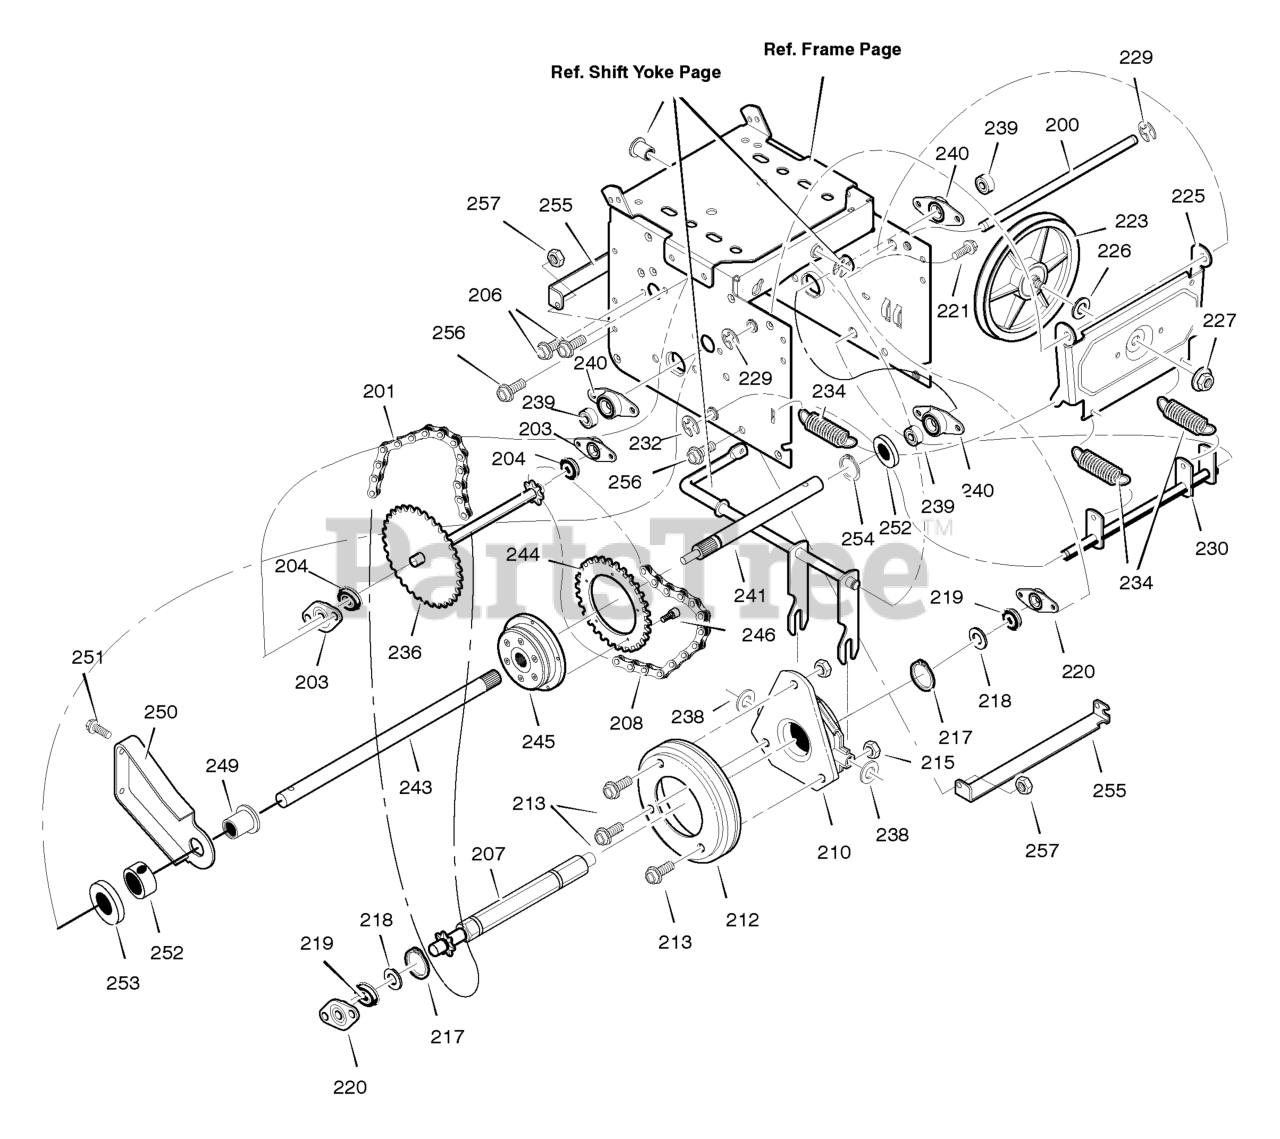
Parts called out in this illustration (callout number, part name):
200	LF AXLE, SWING PLATE YZ
201	CHAIN, ROLLER #420 x 19.00
203	RETAINER ASSY, BEARING
204	BEARING
206	SCREW, TAP 5/16-18 x 0.5
207	ASSY, HEX SHAFT
208	CHAIN, ROLLER #420x18.00 LG
210	BEARING, TRUNION CLUTCH R
212	WHEEL, FRICTION DISC
215	NUT, KEPS HEX 1/4-20
217	RING, RETEXT
219	BEARING, BALL
220	RETAINER, BEARING
221	SCREW, TAP 5/16-18 x .5
223	FRICTION PULLEY
225	LF PLATE, SWINGING YZ
226	SPACER, FRICTION PULLEY
227	NUT, FLANGE LOCK 3/8-24
229	RETAINER, RING
230	ASSY., SPRING LINK -STEERABLE
232	RETAINER, RING
234	SPRING, EXTENSION
236	SPROCKET SET 33T/7
238	WASHER, FLAT
239	BEARING, BALL
240	RETAINER, BEARING
241	AXLE & PIN ASSY. -STEER BB LEFT
243	AXLE & BUSHING ASSY. STEER BB RH
244	SPROCKET
245	CLUTCH, AUTO LOCK
249	BEARING, AXLE
250	BRACKET, AXLE SUPPORT
251	SCREW
252	COLLAR, LOCKING
254	RETAINER, RING
255	BRACKET, SUPPORT
257	NUT
